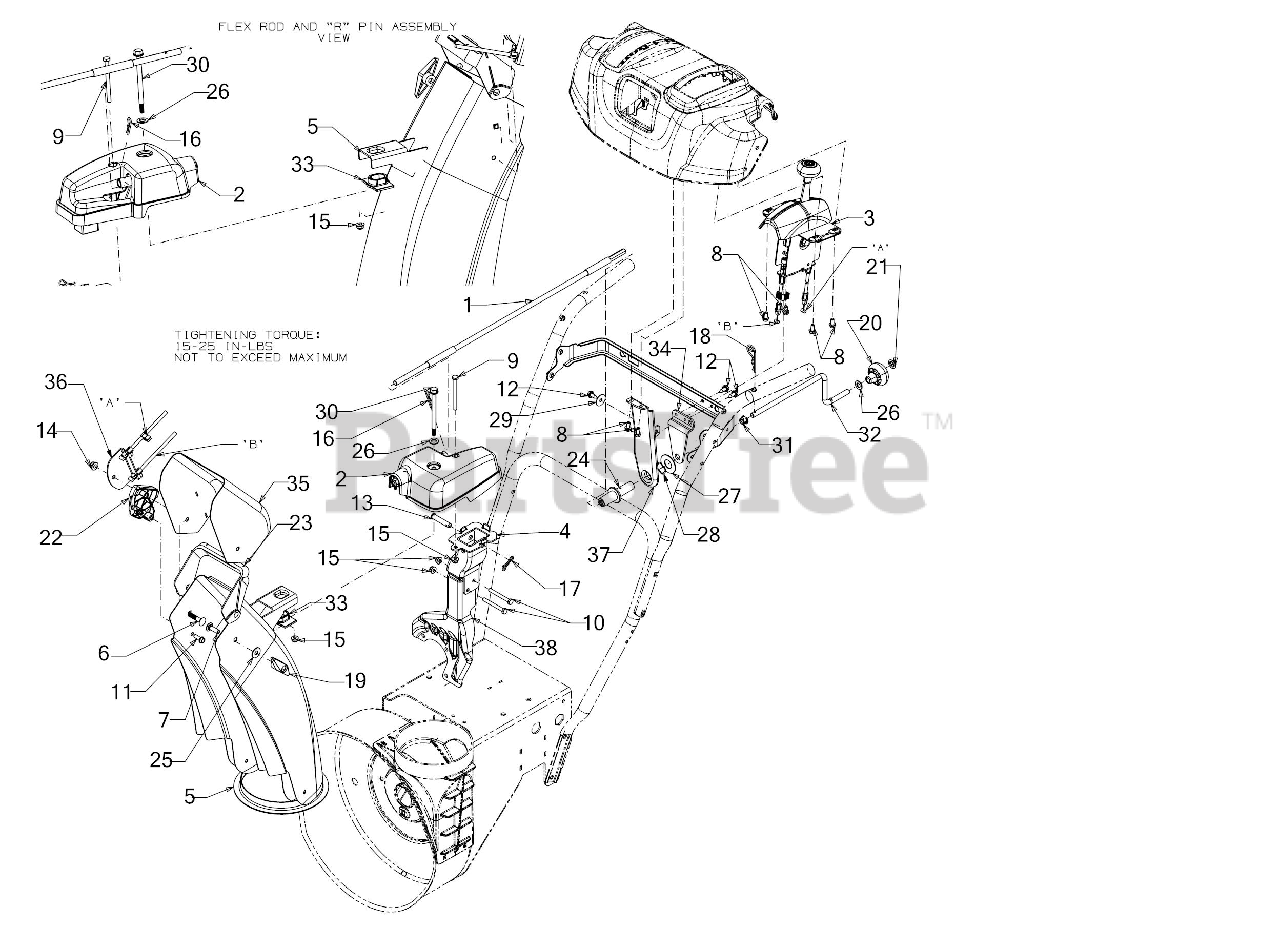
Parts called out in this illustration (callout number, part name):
1	CHUTE CONTROL SHAFT
2	WORM GEARBOX ASSEMBLY
3	2-WAY TALL CHUTE CONTROL ASSEMBLY
4	CHUTE MAST BRACKET
5	LOWER STEEL CHUTE 6" DIA
6	CARRIAGE BOLT 5/16-18 x 1.50
7	CARRIAGE BOLT 5/16-18 x 1.00
8	HEX SCREW 1/4-15 x .50
9	SCREW 1/4-20 x 3.0 GR5
10	SCREW 1/4-20 x 2.25 GR5
11	SCREW 1/4-15 x .750
12	SCREW 1/4-20X.625
13	CLEVIS PIN 3/8 x 1.87
14	FLANGE LOCK NUT 5/16-18
15	FLANGE LOCK NUT
16	INTERNAL COTTER PIN
17	BOW TIE COTTER PIN 1/4-5/16
18	INTERNAL COTTER PIN
19	WING NUT KNOB
20	SHIFT KNOB
21	PUSH NUT
22	CHUTE TILT GUIDE
23	UPPER CHUTE ADAPTER
24	CHUTE ROD COUPLER
25	FLAT WASHER
26	FLAT WASHER
27	FLAT WASHER
28	WAVE WASHER .785X1.00X.012
29	FLAT WASHER
30	SHOULDER SCREW
31	BUSHING .380 ID
33	HELICAL GEAR CHUTE ADAPTER
34	ROD SUPPORT BRACKET
35	UPPER CHUTE STEEL
36	CABLE BRACKET GUIDE
37	CHUTE CONTROL BRACKET
38	CHUTE SUPPORT BRACKET
